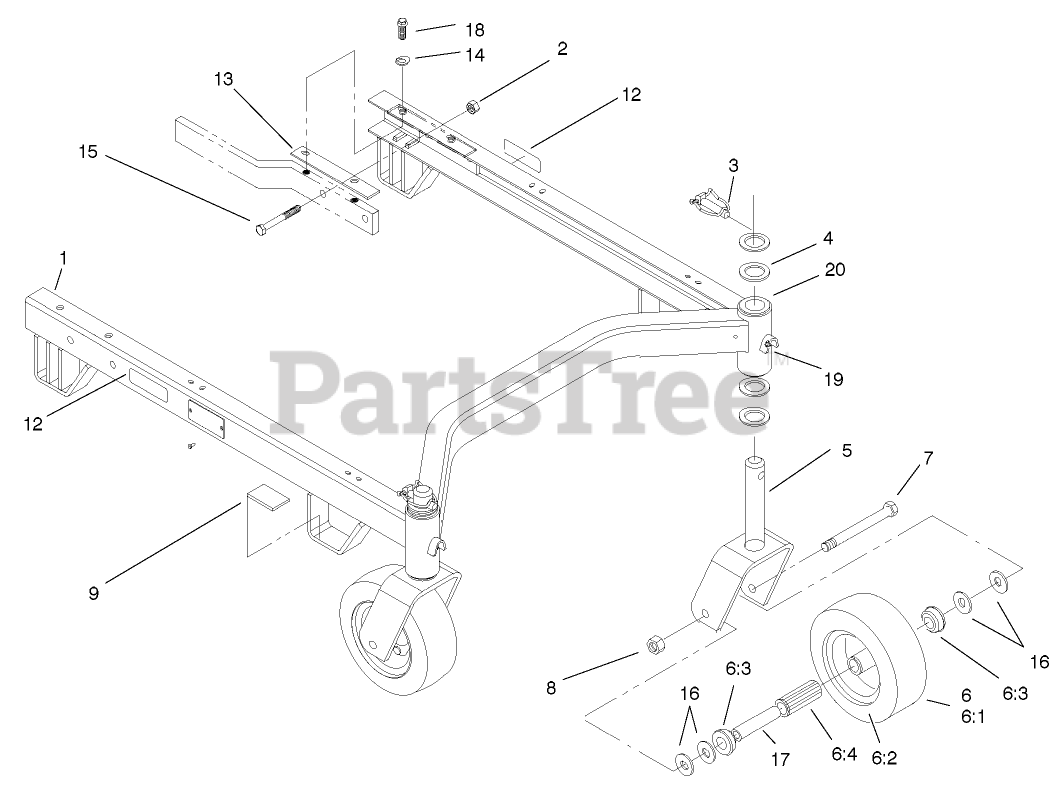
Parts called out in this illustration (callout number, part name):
1	SUSPENSION ASM, GM120
2	NUT-LOCK, CONE
3	PIN-LYNCH
4	WASHER-THRUST
5	FORK-CASTER, FRONT
6	CASTOR WHEEL ASM
6:1	TIRE-TUBELESS
6:2	RIM ASM
6:3	BEARING-OUTSIDE
6:4	BEARING-ROLLER
7	SCREW-HH
8	NUT-HEX
9	CUSHION-RUBBER
12	DECAL-HOC
13	SHIM-CARRIER
14	WASHER-FLAT
15	SCREW-HH
16	WASHER-FLAT
17	SPANNER-TIRE
18	SCREW-HHF
19	FITTING-GREASE
20	BUSHING
